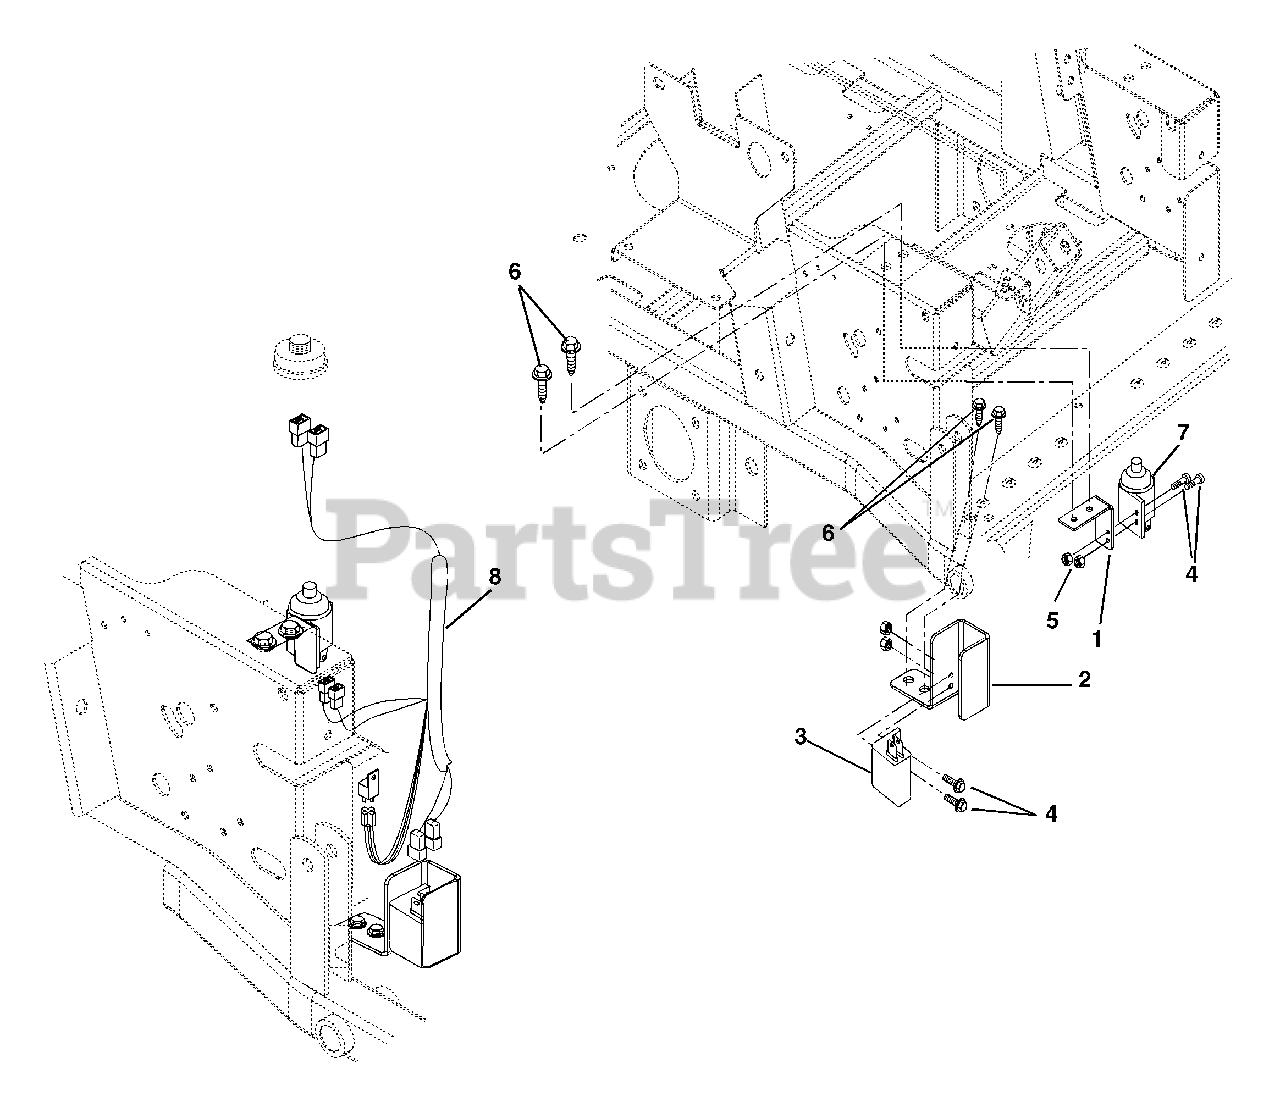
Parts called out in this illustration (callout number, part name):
1	Mount-Switch
2	Bracket-Switch
3	Switch-Single Pole N.O.
4	Screw-Machine 10 - 24 x .75 Hex Washer Head
5	Nut-Lock-Nylon 10 - 24 With Insert
6	Screw-Tap .31 x 18 x .50 Hex Washer Head
7	Switch-Single Pole N.O. with Cover
8	Wire Harness-CE Adaptor
